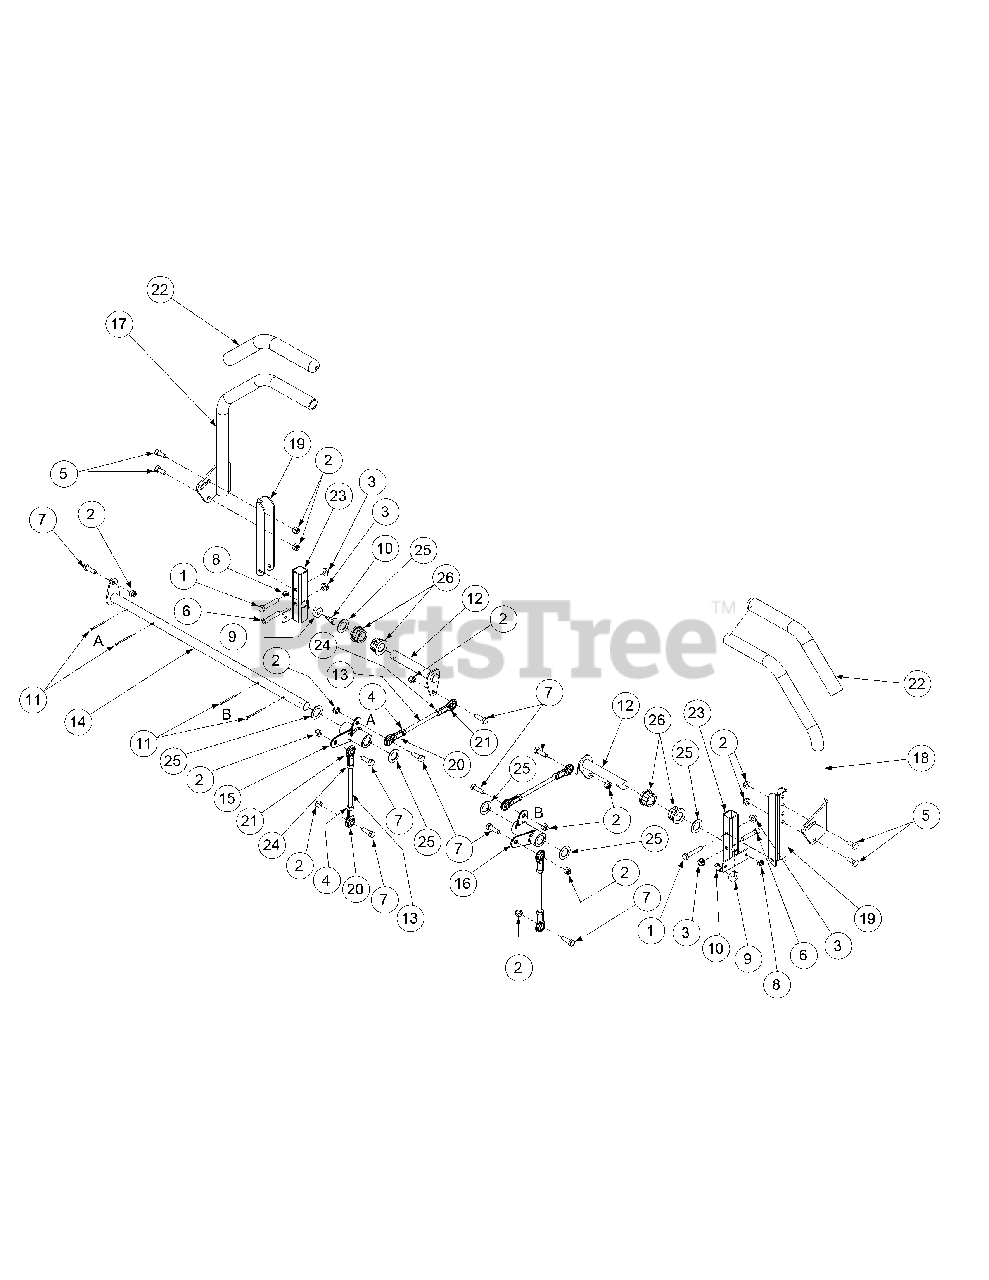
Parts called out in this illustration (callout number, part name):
1	Hex Cap Screw, 5/16-18 x 1-3/4
2	Nut, 5/16-18, Nylock
3	Nut, 5/16-18, Lock
4	Hex Nut, 5/16-24
5	Hex Cap Screw, 5/16-18 x 3/4
6	Capscrew, 5/16-18 x 1.50, Socket Head
7	Hex Cap Screw, 5/16-18 x 1.0
8	Nut, 1/4-28, SS, Nylon Insert
9	Control Rod Spacer
10	Shoulder Screw, 1/4-28
11	Cotter Pin, .125 Dia. x 1.0
12	Steering Input Shaft Assembly
13	Steering Link Rod
14	Bellcrank Steering Shaft Assembly
15	Steering Bellcrank Assembly Left Hand
16	Steering Bellcrank Assembly Right Hand
17	Steering Handle Assembly Left Hand
18	Steering Handle Assembly Right Hand
19	Steering Pivot Bracket
20	Rod End, 5/16, Right Hand
21	Rod End, 5/16, Left Hand
22	Lap Bar Grip
23	Pivot Bracket Weldment
24	Hex Nut, 5/16-24, Left Hand
25	Flat Washer, .793 ID x 1.24 OD x .060
26	Hex Flange Bearing, .752 ID
